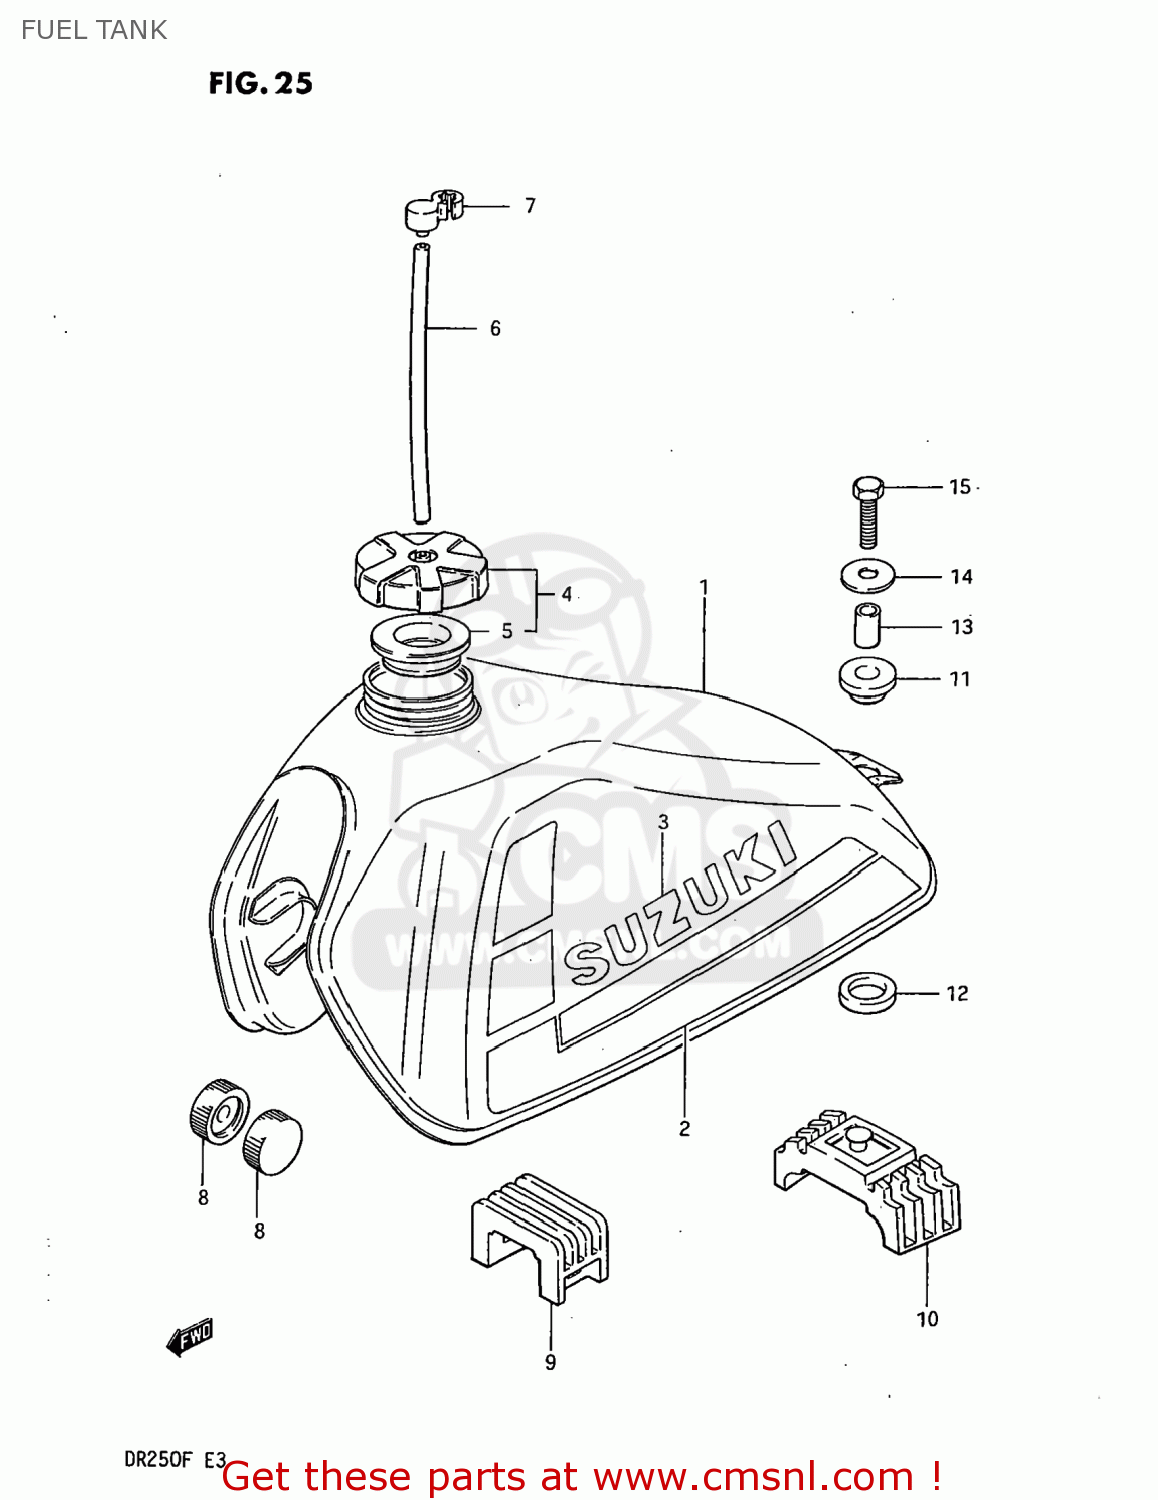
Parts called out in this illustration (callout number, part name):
1	TANK ASSEMBLY,FUEL
2	TAPE SET,FUEL TANK
3	EMBLEM
4	CAP SET,FUEL TANK
5	GASKET (NAS)
6	HOSE
7	CLAMP,FUEL TANK BREATHER HOSE
8	CUSHION
9	CUSHION,TANK UPR FR
10	CUSHION,FUEL TANK,REAR
11	CUSHION
12	CUSHION
13	SPACER(8.5X12X19)
14	WASHER (8.5X29X1.6)
15	BOLT (8X30)
